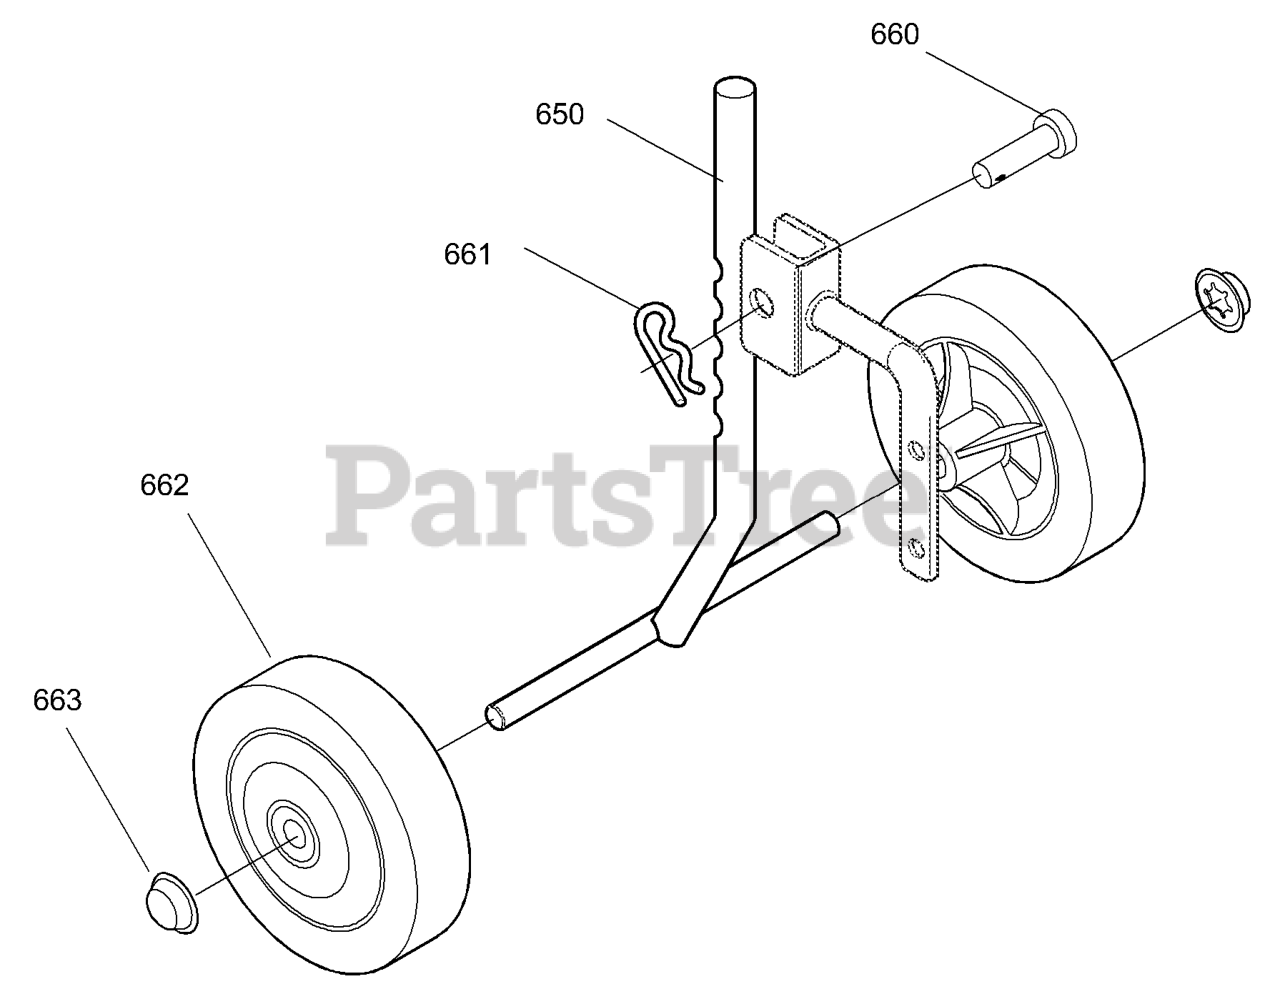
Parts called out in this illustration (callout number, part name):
650	Wheel Support Assy.
660	Clevis Pin
661	Hair Pin
662	Tire & Rim
663	Push On Nut
